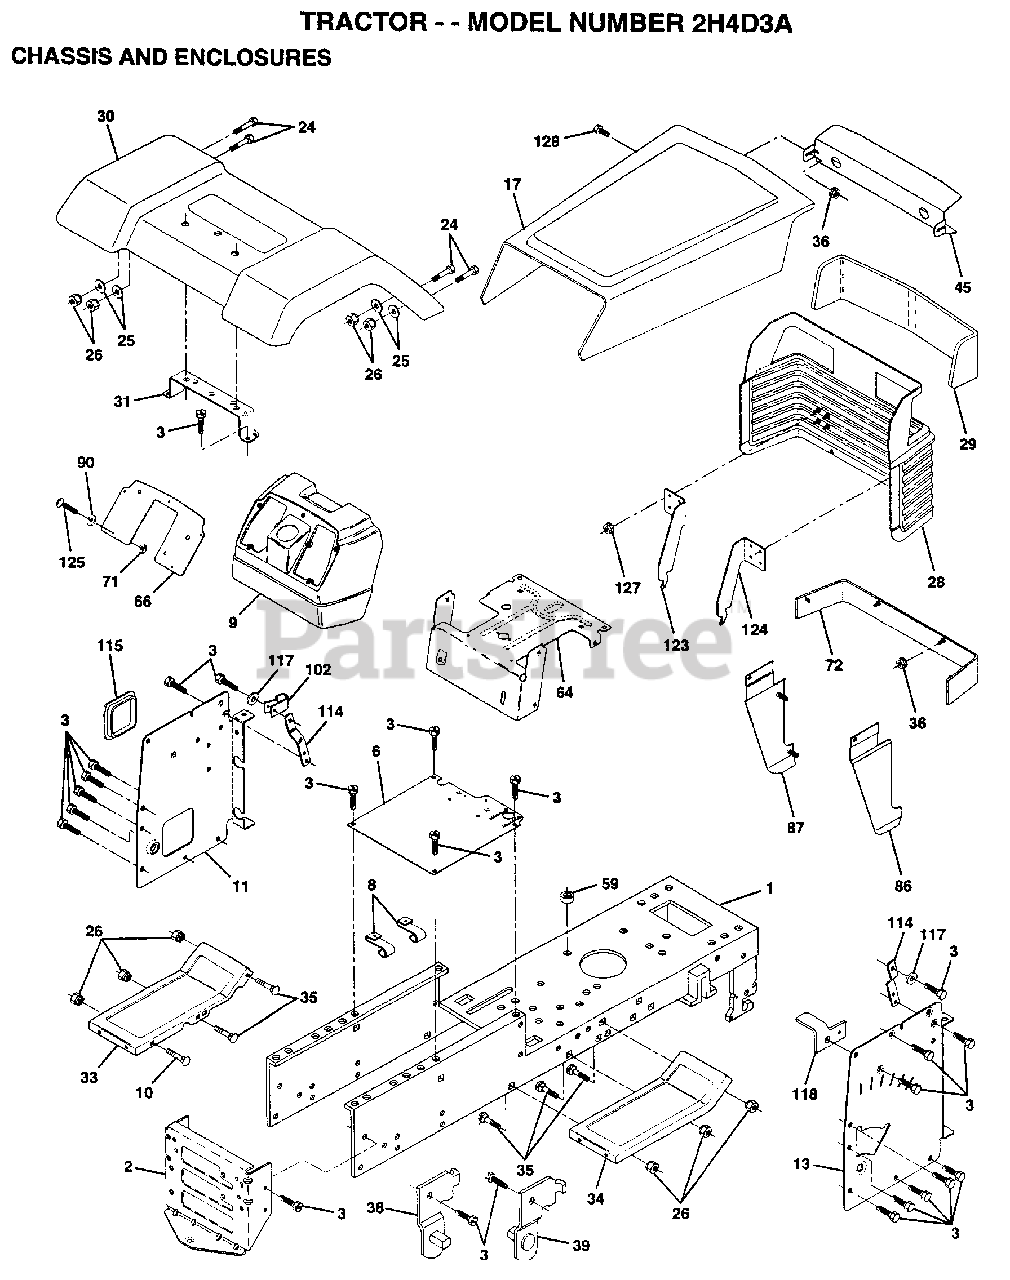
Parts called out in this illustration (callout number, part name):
1	CHASSIS.WLD.11GA
3	SCREW
8	CLIP,INSULATOR
9	DASH.PLASTIC.BLK
11	PANEL.DASH.RH.NOT
17	HOOD.ASM.YTGT.PNT
24	BOLT
25	WASHER
26	NUT
28	GRILLE ASM WELD
29	LENS T
30	FENDER
31	BRKT FENDER
33	FOOTREST LH
34	FOOTREST RH
35	BOLT
36	PAL NUT LT
38	BRACKET ASM LH
39	BRACKET ASM RH
59	Bushing Snap Split
66	PLATE DASH SILKSC
71	NUT HXKEP 1/4X20
72	STRAP GRILLE 505
86	PANEL.SIDE.RH.ASM
87	PANEL.SIDE.LH.ASN
90	WASHER PM
102	CLIP T
114	BRACKET.SUPT.DASH
115	COVER ACCESS
117	WASHER.SERRATED.
118	BRACKET.CLUTCH.MC
124	BRACKET.PICK.RH
125	SCREW
127	PAL NUT
128	SCREW SPECIAL
